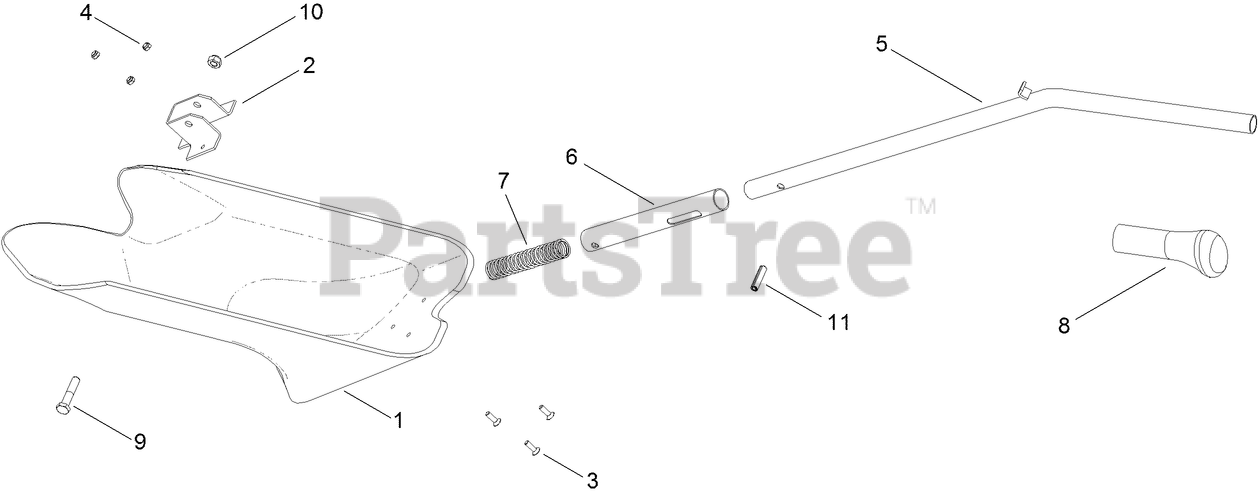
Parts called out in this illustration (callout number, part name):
1	SHIELD-MULCHING
2	BRACKET-SHIELD, MULCHING
4	NUT-LOCK
5	HANDLE-MULCHING, TOP
6	HANDLE-MULCHING, BOTTOM
7	SPRING, MULCHING
8	HANDLE-MULCHING
9	SCREW-HH
10	NUT-LOCK, NI
11	PIN-SPIRAL
